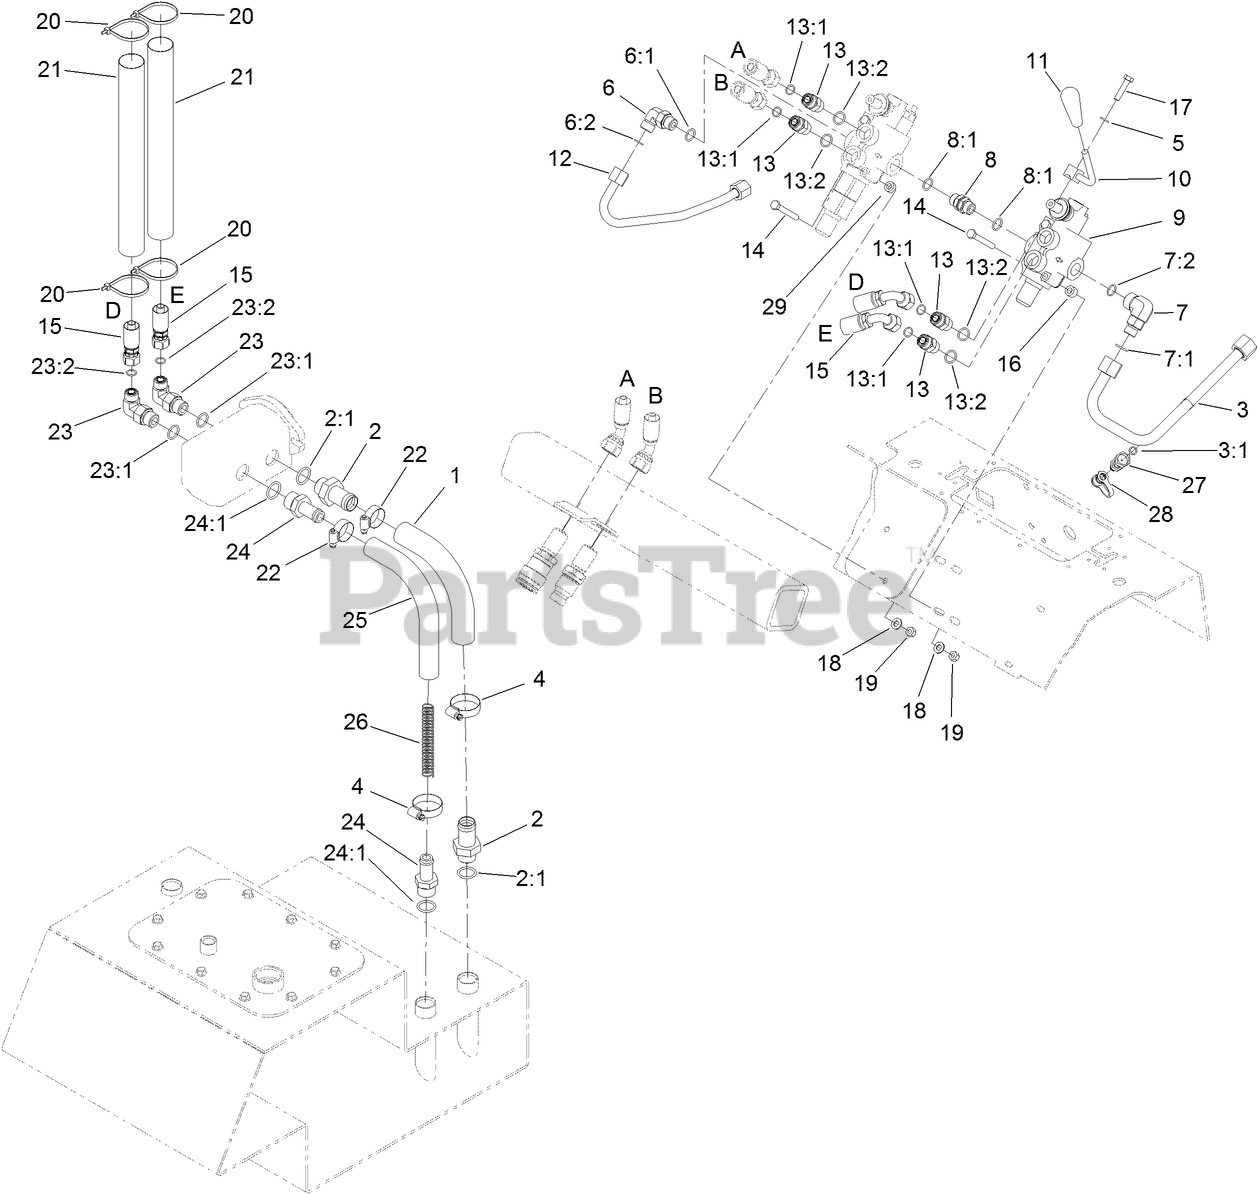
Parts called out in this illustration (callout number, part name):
1	HOSE-SUCTION, FORMED
2	FITTING
2:1	O-RING
3	HYD TUBE ASM
3:1	O-RING
5	WASHER-LOCK
6	FITTING-ELBOW-90 DEG
6:1	O-RING
6:2	O-RING
7	Fitting-Elbow, 90 DEG
7:1	O-RING
7:2	O-RING
8	FITTING-THREAD, STRAIGHT
8:1	O-RING
9	VALVE-SELECTOR, HYD
10	LEVER-CONTROL
11	KNOB-TAPERED
12	TUBE-HYD
13	FITTING-STRAIGHT
13:1	O-RING
13:2	O-RING
14	SCREW-HH
15	HOSE-HYD
16	SPACER
17	SCREW-HH
18	WASHER-PLAIN
19	NUT-LOCK, NI
20	TIE-CABLE
21	SLEEVE-THERMAL
22	CLAMP-HOSE
23	FITTING-ELBOW 90
23:1	O-RING
23:2	O-RING
24	FITTING-STRAIGHT
24:1	O-RING
25	HOSE-SUCTION, HYD
26	Spring-Compression
27	NIPPLE-TEST
28	CAP-DUST
29	SPACER
